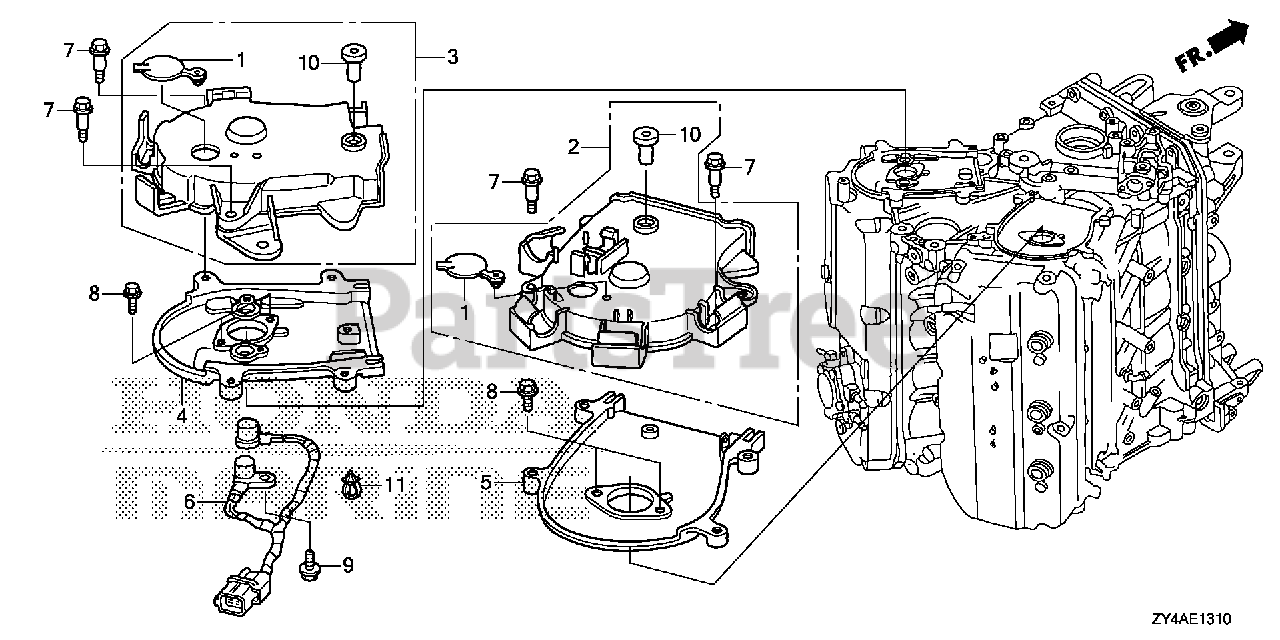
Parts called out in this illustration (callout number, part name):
1	GROMMET, TIMING BELT COVER
2	COVER ASSY., R. TIMING BELT
3	COVER ASSY., L. TIMING BELT
4	PLATE, L. TIMING BELT COVER
5	PLATE, R. TIMING BELT COVER
6	SENSOR (TDC1-TDC2)
7	BOLT, TIMING BELT COVER
8	BOLT, SPECIAL (8X29)
9	BOLT, FLANGE (5X14)
10	COLLAR, TIMING BELT COVER
11	CLIP, HARNESS BAND (145MM) (BLACK)
